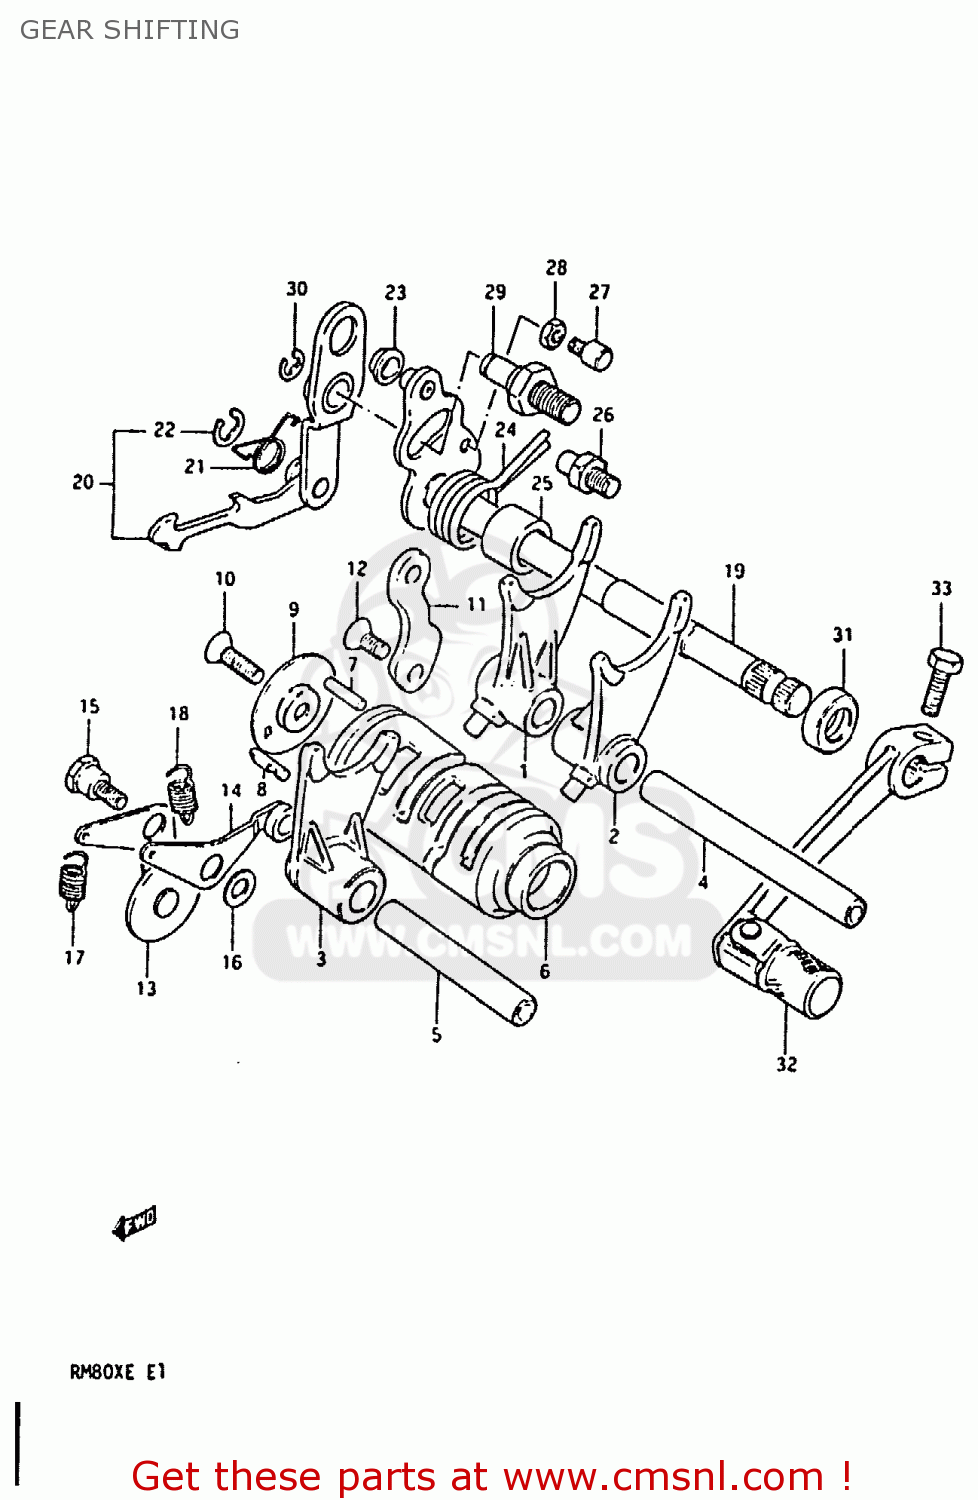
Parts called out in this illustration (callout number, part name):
1	FORK,GEAR SHIFT NO.1
2	FORK,GEAR SHIFT NO.2
3	FORK,GEAR SHIFT NO.2
4	SHAFT,GEAR SHIFT FORK
5	SHAFT,GEAR SHIFT FORK
6	CAM,GEAR SHIFT
7	PIN(4X15.8)
8	PIN
9	RETAINER,GEAR SHIFT CAM
10	SCREW
11	GUIDE,GEAR SHIFTING CABLE
12	SCREW
13	STOPPER,SHIFT CAM
14	STOPPER,GEAR SHIFT CAM
15	BOLT(6X18.3)
16	WASHER
17	SPRING
18	SPRING
19	SHAFT,GEAR SHIFT
20	PAWL,GEAR SHIFT
21	SPRING
22	E RING
23	SPACER(7X10X5)
24	SPRING
25	SPACER(12X20X15.3)
26	STOPPER,GEAR SHIFT CAM
27	BOLT,GEAR SHAFT RETURN SPR SET
28	NUT 6MM
29	STOPPER,GEAR SHIFT CAM
30	E RING 6MM
31	OIL SEAL
32	LEVER ASSEMBLY,GEAR SHIFTING
33	BOLT
